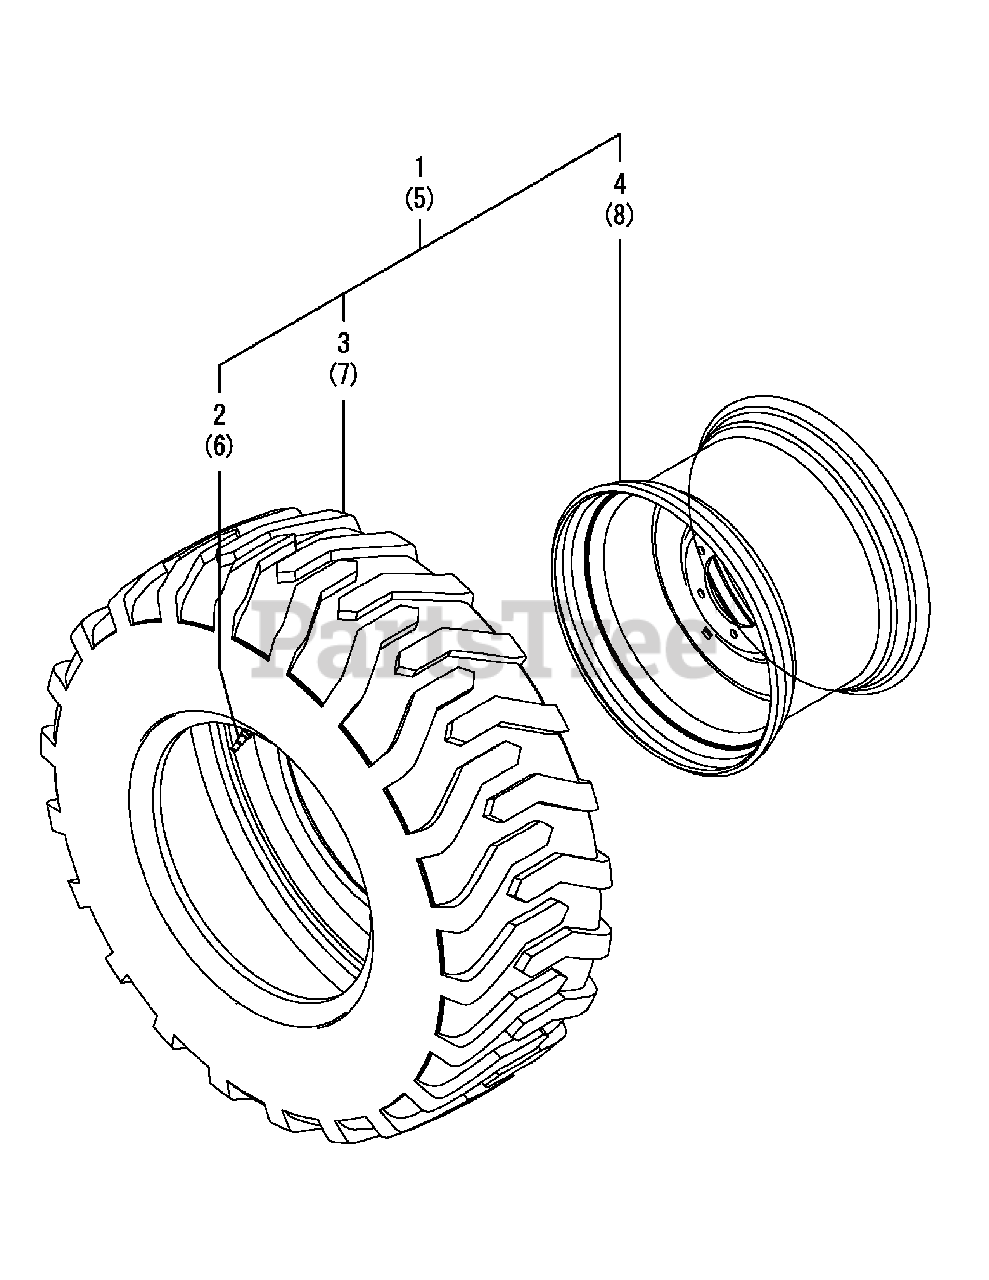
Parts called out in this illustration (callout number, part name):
1	Tire Assembly, Rear L R4
3	Tire, 14X17.5 R4
5	Tire Assembly, Rear R R4
7	Tire, 14X17.5 R4
